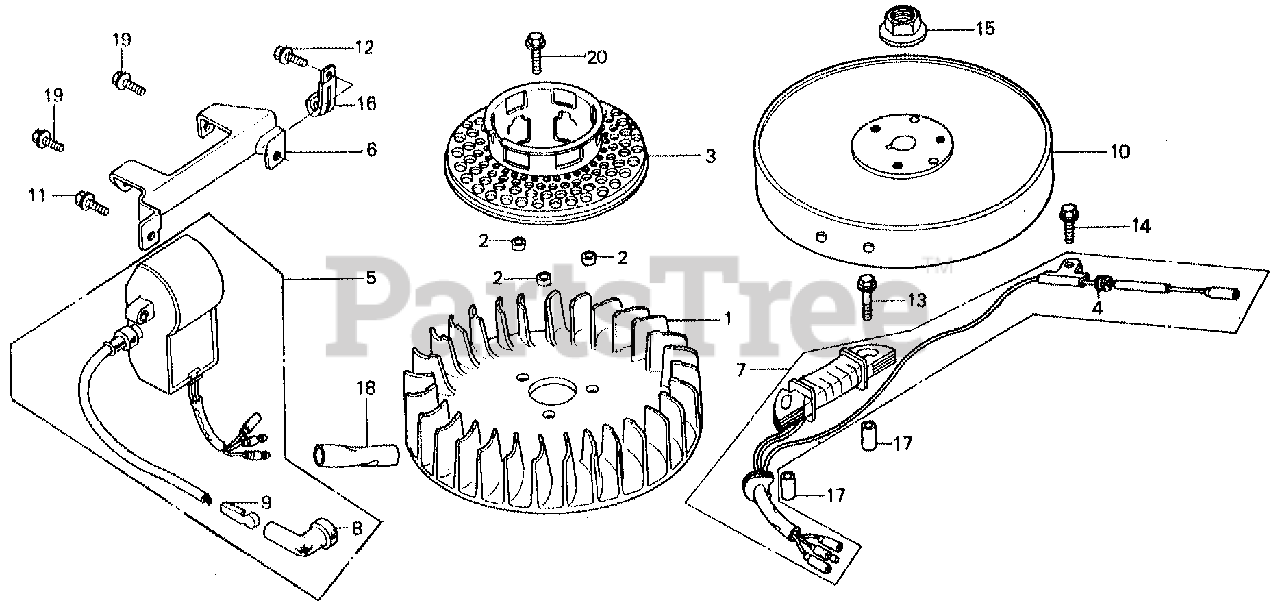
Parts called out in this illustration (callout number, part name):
1	FAN, COOLING
2	COLLAR, FAN
3	PULLEY, STARTER
4	GROMMET, PRIMARY WIRE
5	MODULE, IGNITION CONTROL (CDI)
5	MODULE, IGNITION CONTROL (CDI) (NOT AVAILABLE)
6	STAY, IGNITION CONTROL MODULE
7	COIL ASSY., EXCITER
8	CAP, IGNITION (SUMITOMO)
8	CAP, IGNITION (TOYO)
9	TERMINAL, PLUG
10	FLYWHEEL (C.D.I.)
11	BOLT, FLANGE (6X12) (CT200)
12	BOLT, FLANGE (6X14)
13	BOLT, FLANGE (6X28)
14	BOLT, FLANGE (5X10)
15	NUT, SPECIAL (14MM)
16	CLIP, CABLE
17	PIN A, DOWEL (8X14)
18	TUBE, VINYL (16X19X50)
19	BOLT, FLANGE (6X12)
20	BOLT, FLANGE (6X16)
